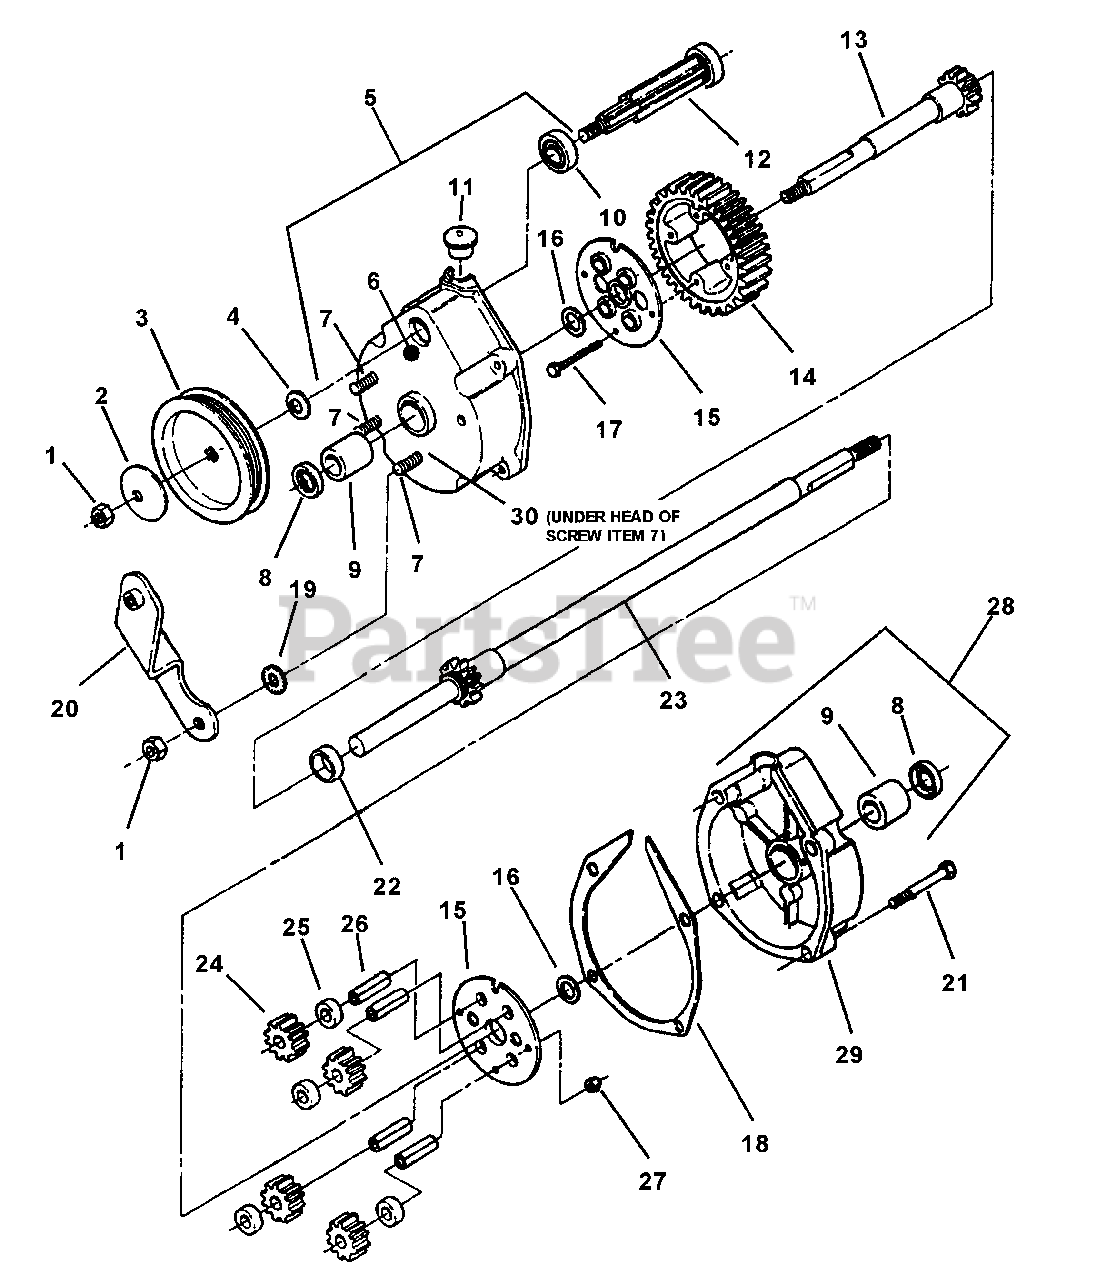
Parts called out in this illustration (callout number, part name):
1	NUT, 5/16-24 Hex Lock
2	WASHER, Spring
3	PULLEY, Poly-Vee Belt
4	WASHER, Spring
5	ASSEMBLY, Housing Right
6	HOUSING, Right Side
7	SCREW, 5/16-24 x 1-1/8" Rib Neck, Grade 5
8	SEAL, 5/8 I.D.
9	BEARING, Differential
10	BEARING, Ball
11	PLUG, Housing
12	GEAR, Input
13	AXLE, Short
14	GEAR, Differential (46 Tooth)
15	PLATE
16	WASHER, Thrust
17	SCREW, #10-32 x 1-1/2" Hex Head Cap,
18	GASKET, Housing
19	WASHER, 5/16 Internal/External Tooth Lock
20	BRACKET, Differential
21	SCREW, 1/4-20 x 1-1/4" Self-Tapping
22	SPACER, Axle Gear
23	AXLE, Long
24	GEAR, Pinion (12 Tooth)
25	SPACER, Pinion Gear
26	SHAFT, Pinion
27	NUT, #10-32 Hex Nyloc
28	ASSEMBLY, Housing Left
29	HOUSING, Left Side
30	GASKET, 5/8 O.D.
